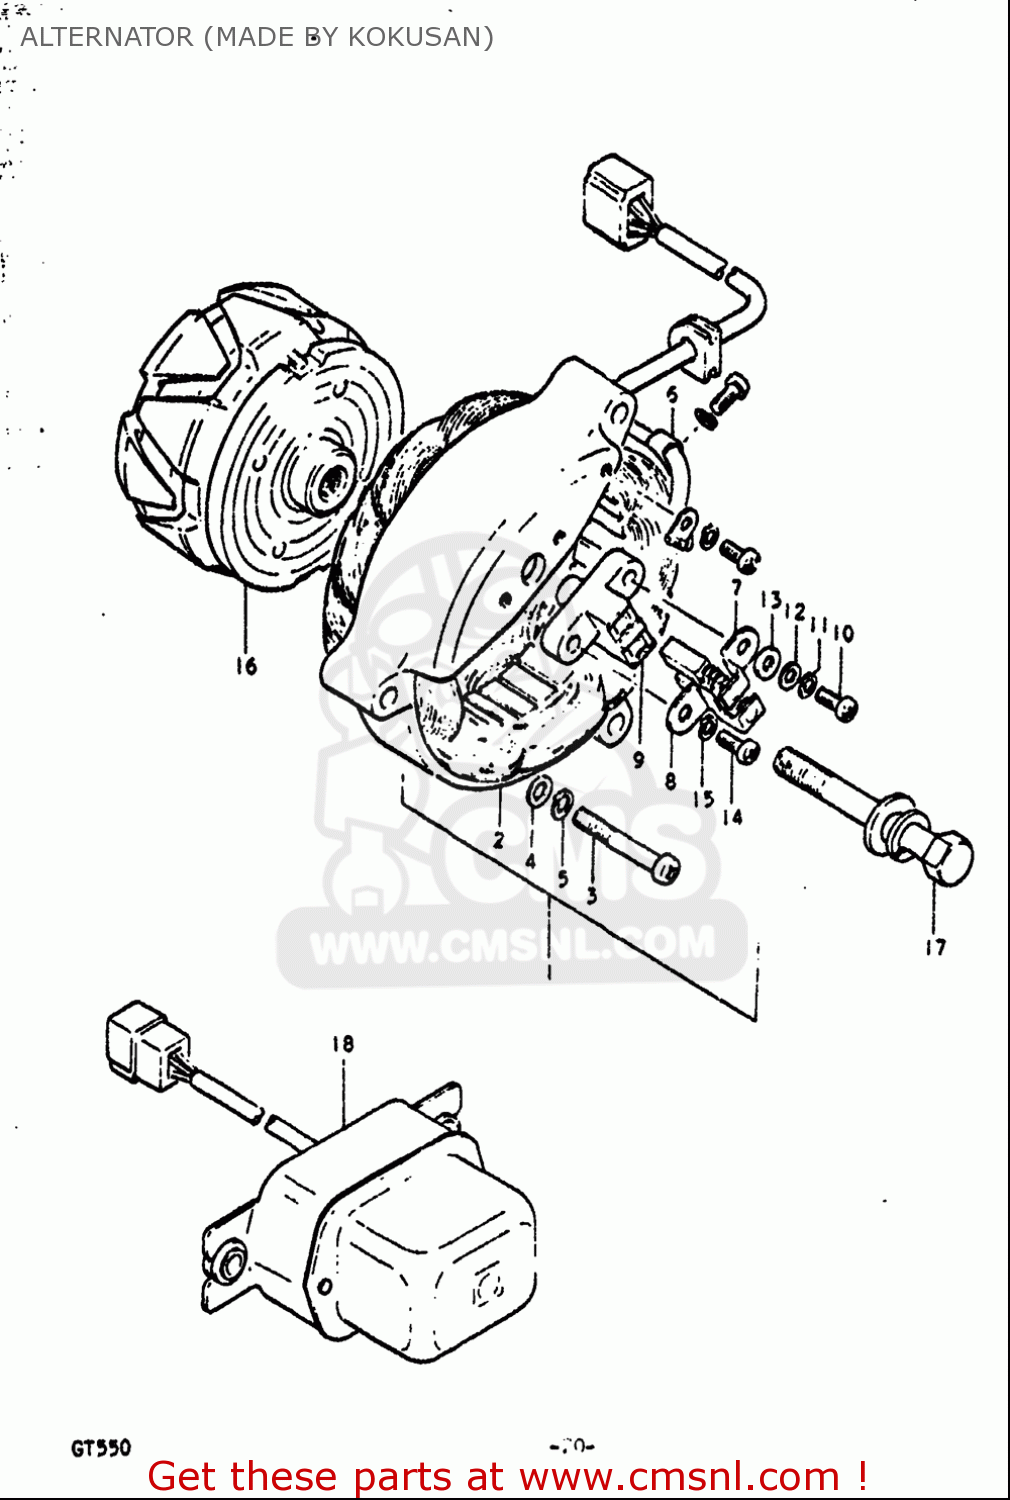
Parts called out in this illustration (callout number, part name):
4	WASHER
5	WASHER,LOCK
7	BRUSH
8	BRUSH
10	SCREW 4X16
11	WASHER,LOCK
12	WASHER
14	SCREW
15	WASHER,LOCK
17	BOLT
